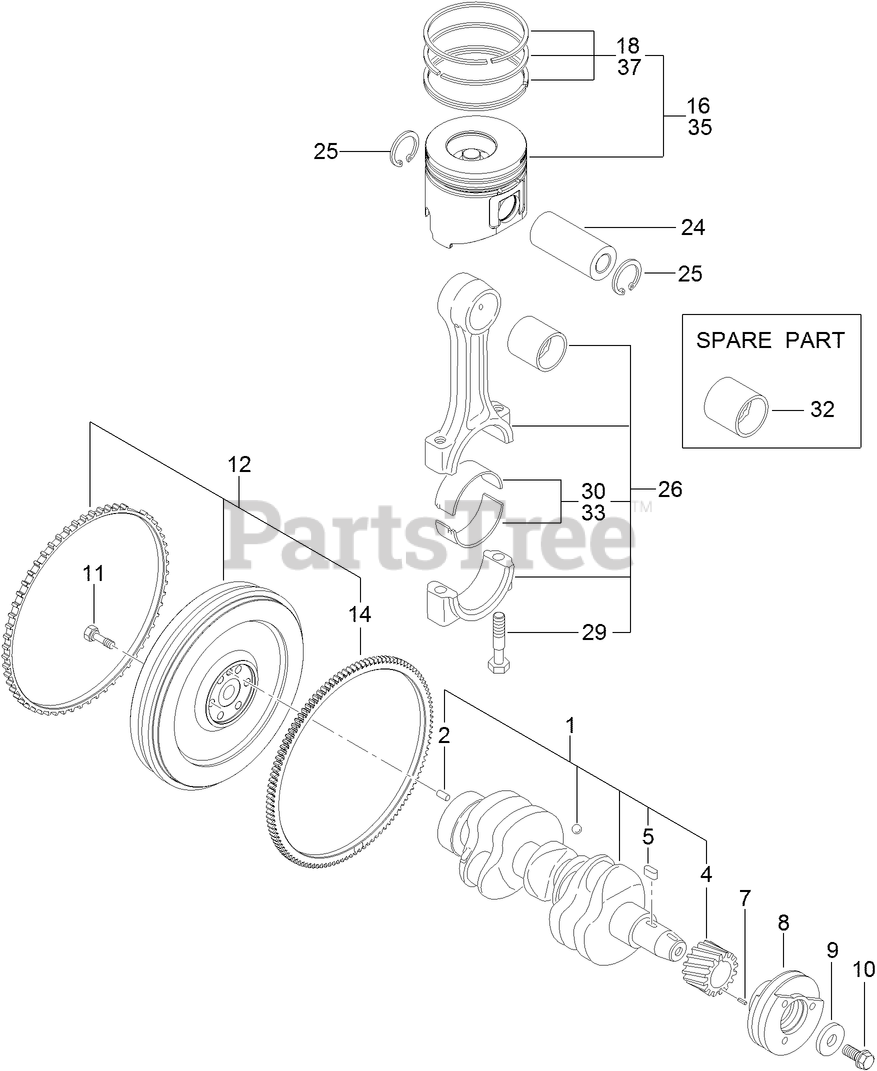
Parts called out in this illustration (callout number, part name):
1	CRANKSHAFT ASM
7	PIN-SPRING
8	PULLEY-V
9	WASHER
12	FLYWHEEL ASM
16	PISTON ASM
18	PISTON RING ASM
26	CONNECTING ROD ASM
30	PIN-CRANK
32	PIN-PISTON
33	PIN-CRANK (.25)
35	PISTON ASM (0.25 O S)
37	RING SET (0.25 O S)
